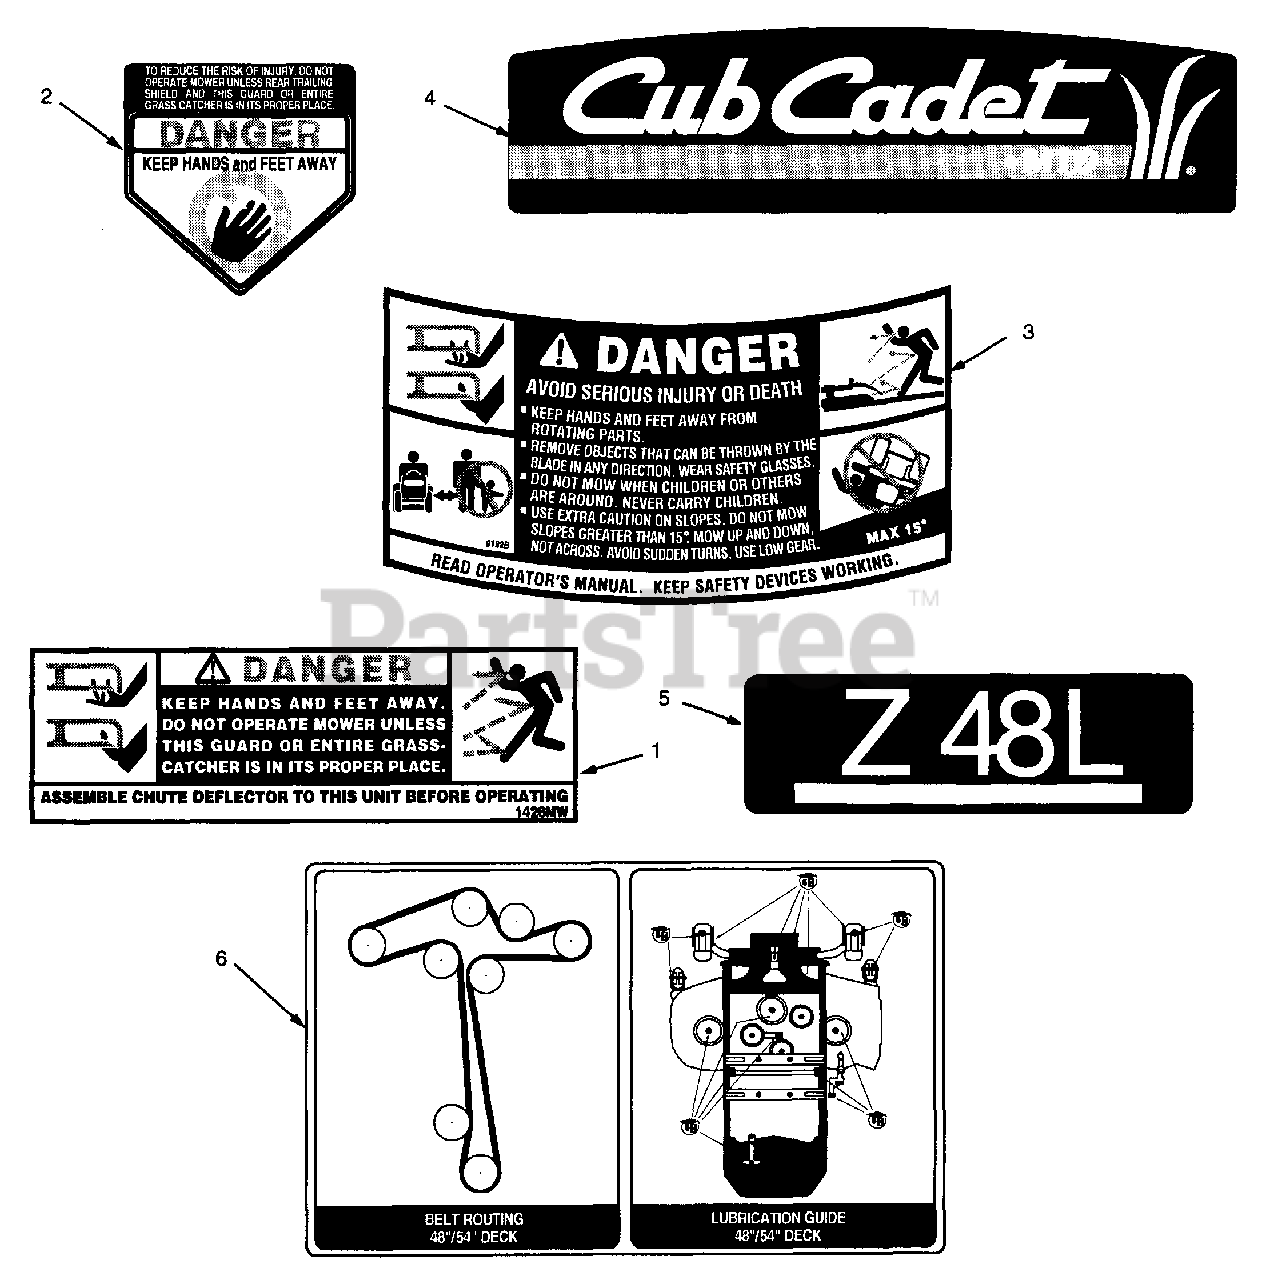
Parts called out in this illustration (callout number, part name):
1	Label, Danger - Top of Deck
2	Label, Danger - Top of Deflector Chute
3	Label, Safety - Top of Deck
4	Label, Model - Back of Seat
5	Label, Safety - Front Steering Console
6	Label, Information - Under Belt Cover
